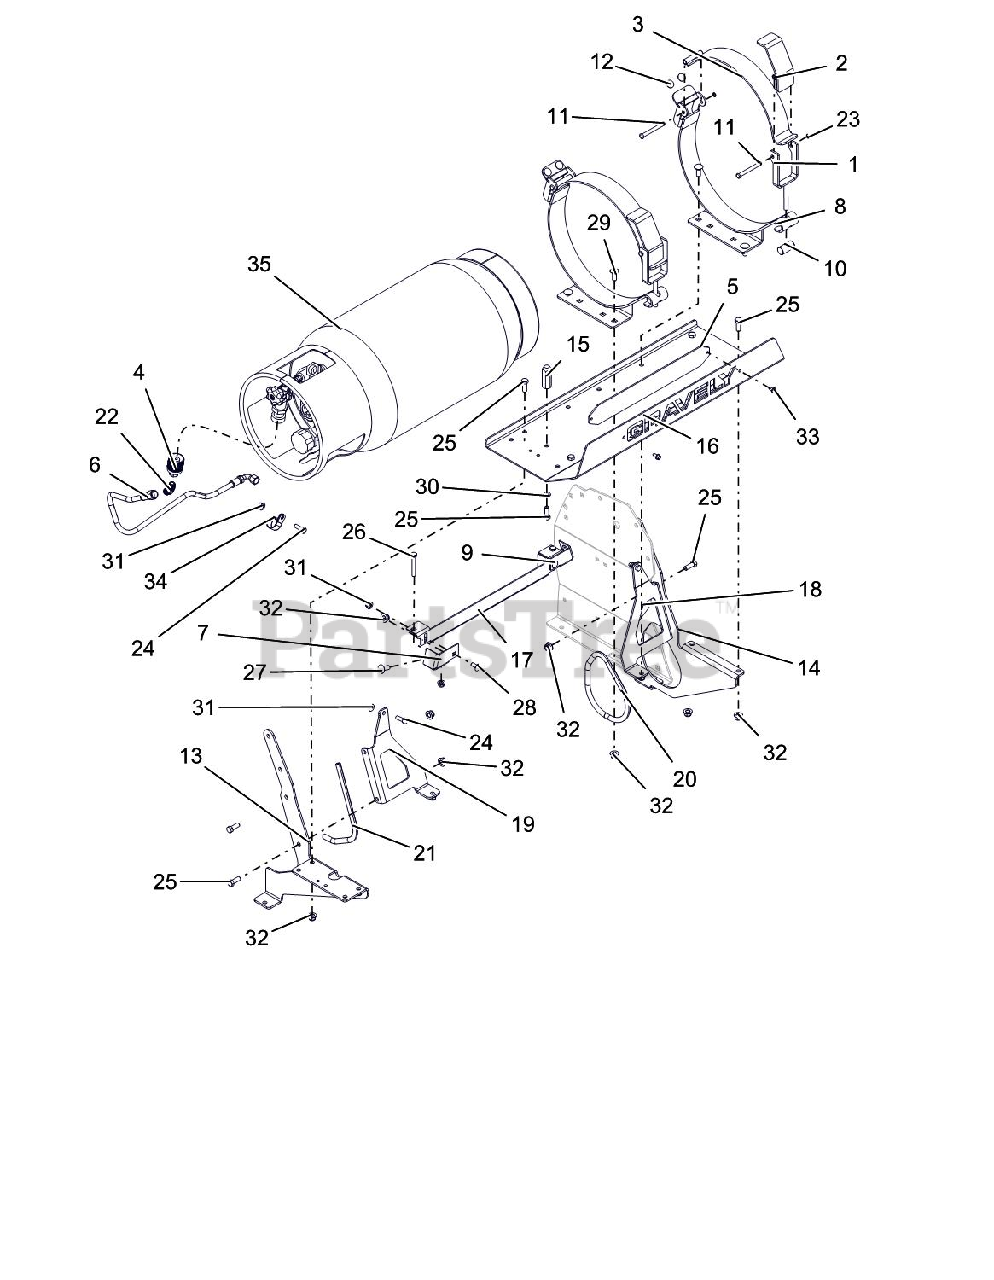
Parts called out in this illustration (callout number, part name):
1	WDMT,TOGGLE,LPG TANK CLAMP
2	WDMT, LEVER, TANK TOGGLE
3	WLDMT, UPPER, LP TANK CLAMP
4	FTG, LPG TANK COUPLER LH THRD
5	BACKER, NAMEPLATE
6	HOSE, LPG SS25UL 6-4-6-30.00
7	MOUNT, FUEL TANK HOLD DOWN-RH
8	WLDMT, CLAMP LP TANK
9	MOUNT, FUEL TANK HOLD DOWN-LH
10	PIVOT, LP CLAMP HANDLE
11	PIN, LP CLAMP
12	MAGNET, .75X.06, LP CLAMP
13	EAR, MOUNT RH
14	EAR, MOUNT LH
15	POST, INDICATOR LP TANK
16	TRAY, PRO-STANCE
17	HOLDDOWN, FUEL TANK
18	BRACE, OPERATOR LH
19	BRACE, OPERATOR RH
20	TRIM, RUBBER EDGE 17.75"
21	TRIM, RUBBER EDGE 11.75
22	FTG, 45 1/4-NPTF 9/16-18 45-FL
23	RG-RTNG-EXT .312X.025
24	@BLT-HEX .31-18X1.00 GR5 YWZC
25	@BLT-HEX .38-16X1.00 GR5 YWZC
26	@BLT-HEX .31-18X2.25 GR5 YWZC
27	@BLT-RDHDSHSQNK.38-16X1.0 G5YZ
28	@BLT-RDHDSQNK .31-18X.75 G5YZ
29	@BLT-RDHDSQNK .38-16X1.00 G5YZ
30	@WSHR-LK .38X.094 REG YWZC
31	@NUT-LK-NYL-FLG .31-18 YWZC
32	@NUT-LK-NYL-FLG .38-16 YWZC
33	SCR-TAP .25-20X.50 HWH TR YWZ
34	CLAMP, COUSHIONED STEEL REV
35	TANK, LP, 33.5 LB VAPOR L&G
